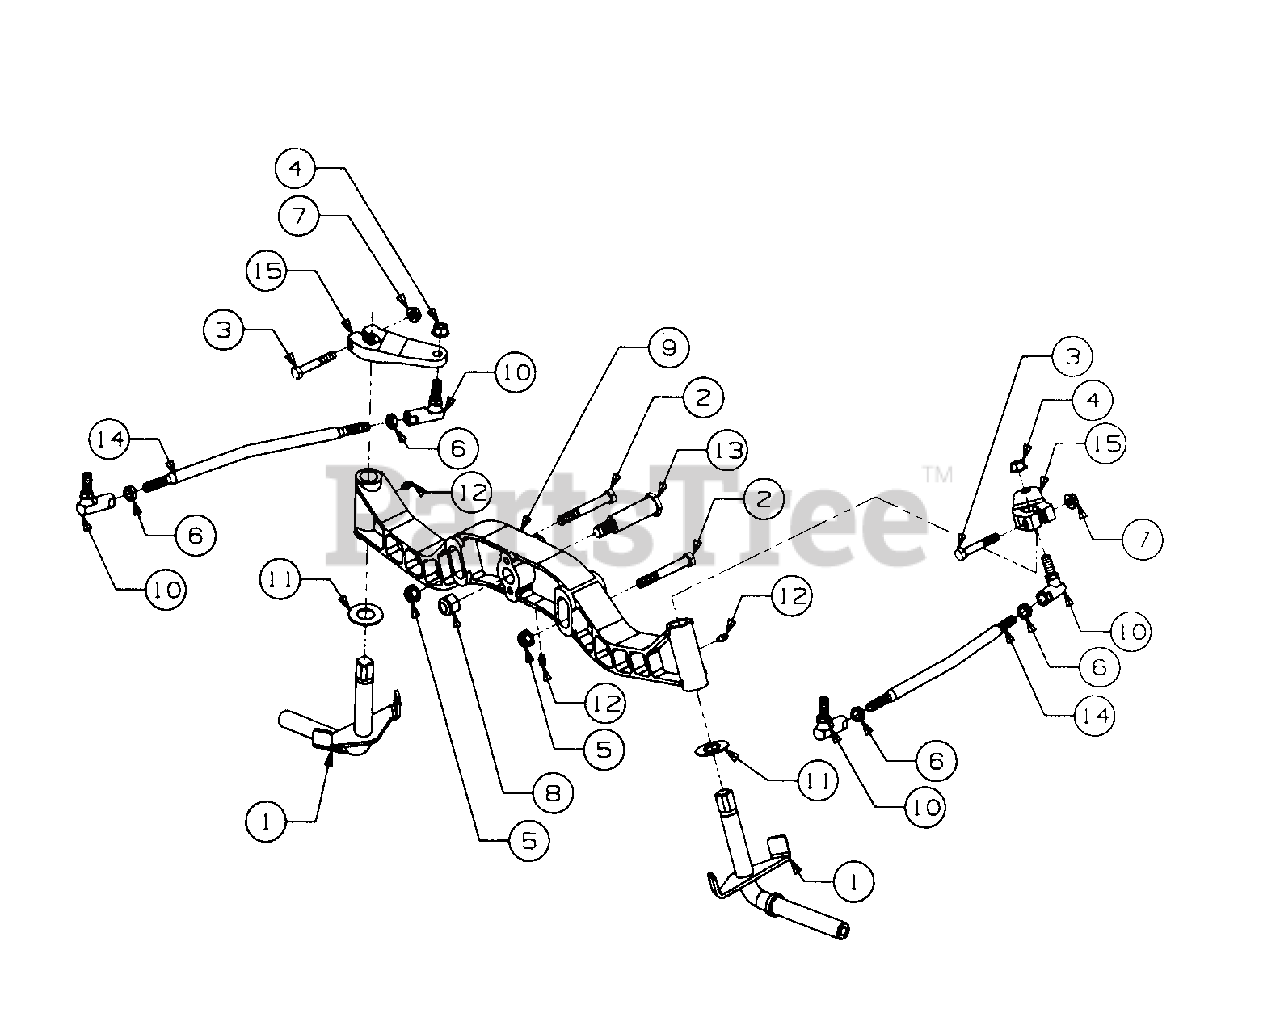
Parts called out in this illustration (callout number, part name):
1	Knuckle Assembly, Steering
2	Screw, Hex Cap, 3/8-16 x 2.75 GR8
3	Screw, Hex Cap, 5/16-18 x 2 GR5
4	Nut, Hex Lock, 3/8-24 GR5
5	Nut, Hex Flanged Lock, 3/8-16
6	Nut, Hex Jam, 3/8-24 GR5
7	Nut, Hex Flange Top Lock, 5/16-18
8	Nut, Hex Top Nylon Lock, 1/2-13
9	Axle, Front Pivot
10	Joint, Ball, 3/8-24
11	Washer, Flat, .760 x 1.49 x .06 Thk.
12	Fitting, Lube, 3/16 Drive Type
13	Bolt, Pivot Shoulder, 3/4 Dia x 2.23
15	Arm, Steering
